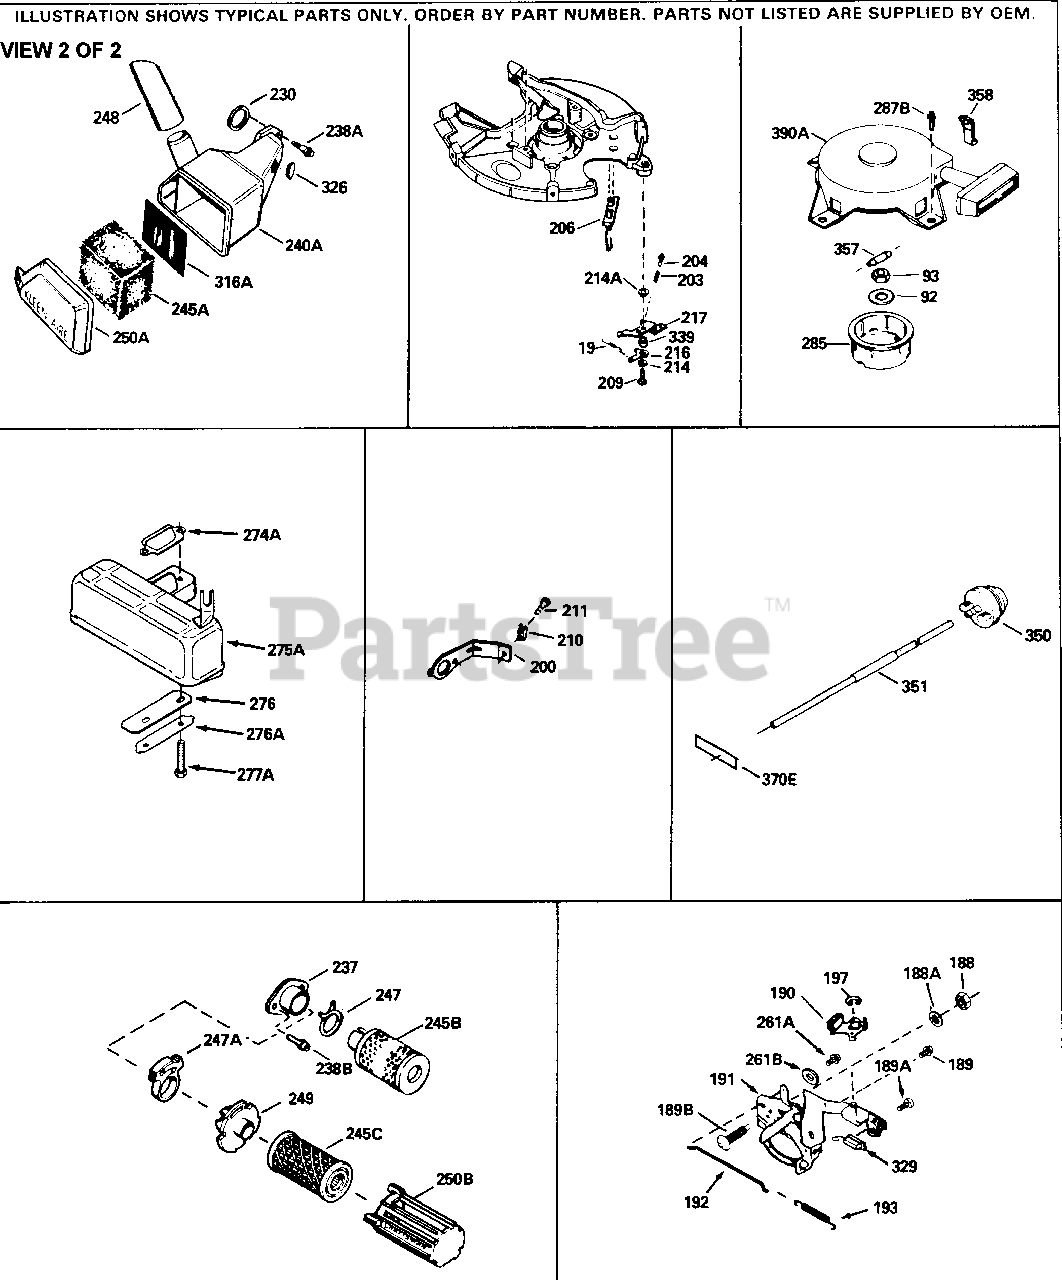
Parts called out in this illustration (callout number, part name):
92	Belleville Washer
93	Flywheel Nut
189A	Screw, Torx T-30, 1/4-20 x 5/8" As re q.
230	Air Cleaner Gasket
238A	Screw, 10-32 x 5/8"
240A	Air Cleaner Body
245A	Air Filter
248	Air Cleaner Tube
250A	Air Cleaner Cover
326	Button Plug
